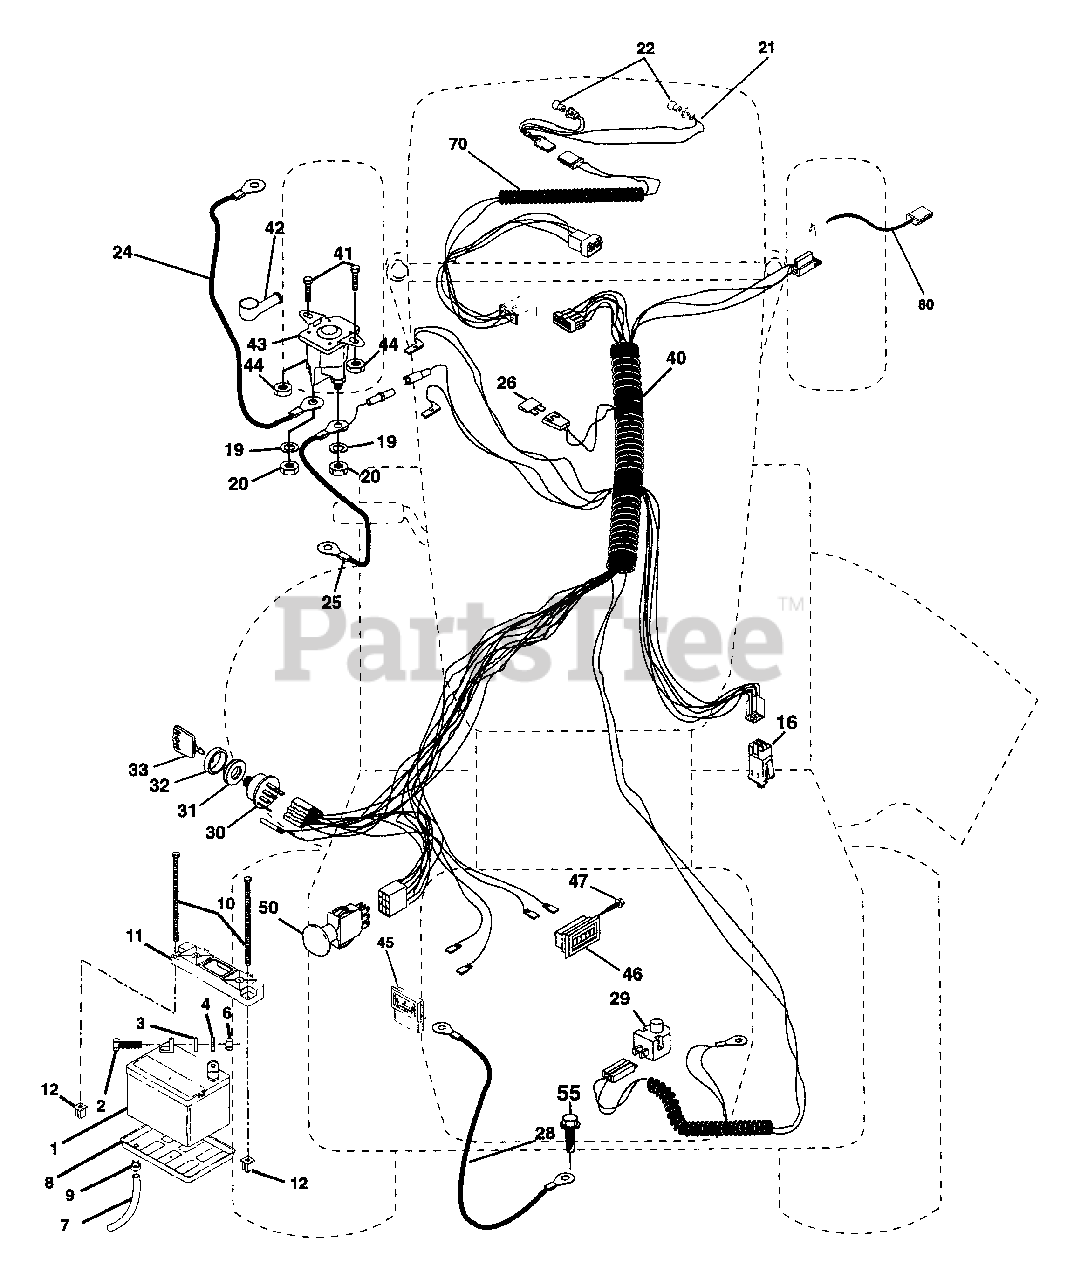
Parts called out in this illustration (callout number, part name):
1	Battery 12 Volt 30 AMP
2	Bolt Hex Hd 1/4-20unc X 3/4
3	Washer 9/32 X 5/8 X 16 Ga.
4	Washer Lock Hvy Helical 1/4
6	Nut Fin Hex 1/4-20 Unc
7	Tube Plastic 46"
8	Tray, Battery 7.80 x 5.25 blk
9	Clamp Hose Olive
10	Bolt, Btr, Front, 1/4-20 x 7.5 Zinc
11	Holddown, Battery Dash Mount
12	Nut, Push, Nylon 1/4" Battery Frt
16	Switch Interlock Push-In
19	Washer Lock 1/4
20	Nut Jam Hex 1/4-20 Unc
21	Harness Asm Light W/4152j
22	Bulb Light #1156
24	Cable Battery 6 Ga 11" red
25	Cable 6 Ga. Red 22" w/16" Wire
26	Fuse 30 AMP Auto Green
28	Cable, Ground 21" Blk 6 Ga. 90T
29	Switch Plunger Nc Gray
30	Switch Ign 4 pos w/lights
31	Nut Ignition
32	Cover Sw Ignition
33	Key Ign Modleded Generic
40	Harness Ign. Elec. HMLT P/L
41	Bolt Blk Fin Hex 1/4 - 20 x 1/2
42	Cover Terminal Red
43	Solenoid
44	Nut Keps Hex 1/4-20 Unc
45	Ammeter Rectangular 6 Amp
46	Meter Hour
47	Screw 10-24 x 1/2 Black
50	Switch PTO 3 PTD Black
55	Screw Thdrol 5/16-18 x 1/2 Tyt
70	Harness, Eng.
80	Harness Clutch EVX
